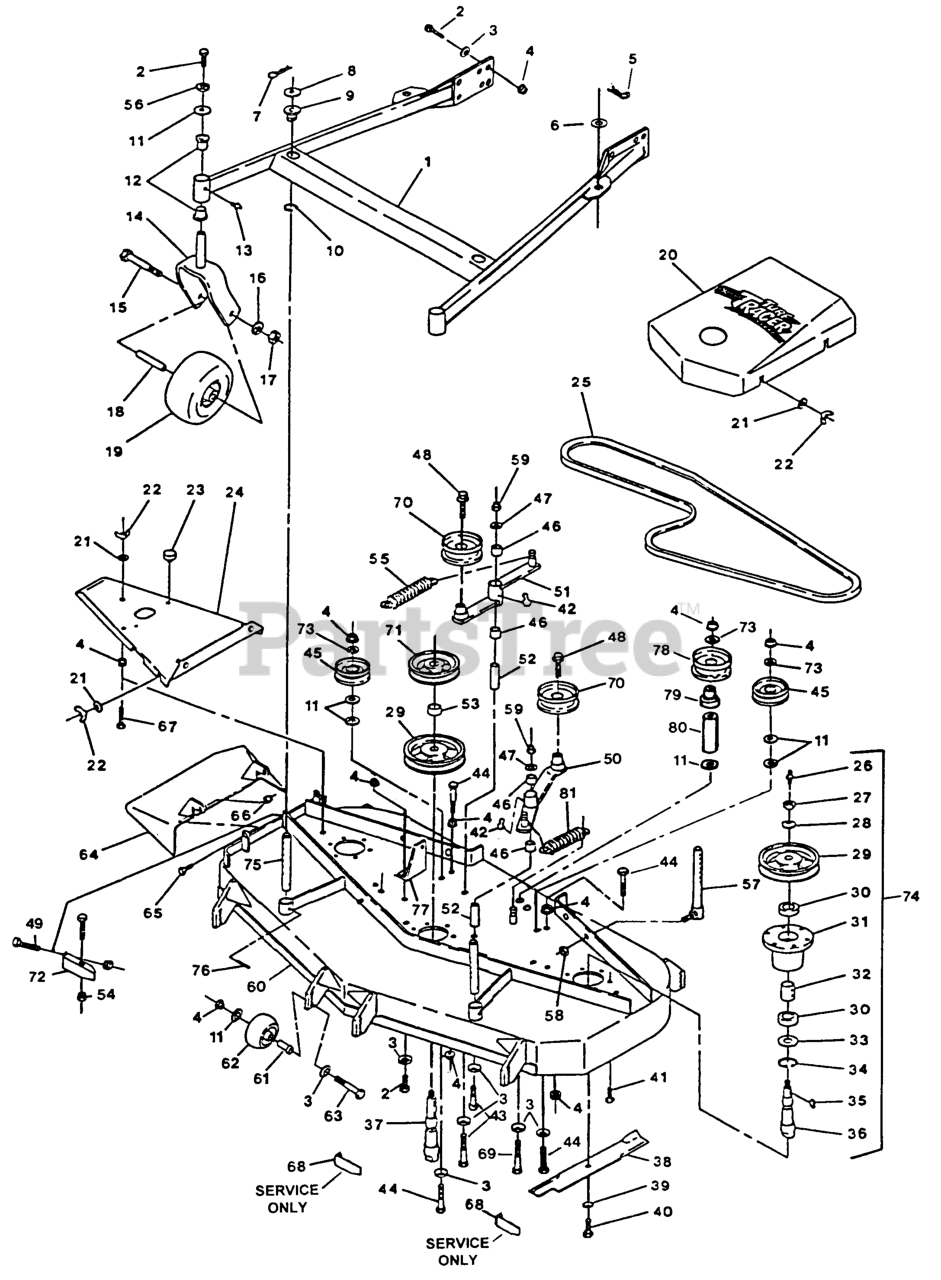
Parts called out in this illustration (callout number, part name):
1	SUPPORT ASSY-FMD60
5	PIN,HAIR COTTER
8	WASHER-FLAT
9	BUSHING-DECK
11	WASHER
12	BEARING-FLANGED
18	SPACER
22	NUT-WING
24	WLD,DECK COVER
25	BELT-DRIVE, BLADE
28	WASHER-SPRING
29	SHEAVE,BLADE DRIVE
32	SPACER,BEARING
33	SEAL,MECHANICAL DUST
34	RING,SNAP WLDS N5000-244
36	SPINDLE-OUTER BLADE
37	SPINDLE-CENTER BLADE
39	WASHER-SPRING
41	SCRW,TPTTE HH
43	SCREW-HH
45	IDLER,PULLEY
46	SLEEVE-BEARING
50	Arm Weldment Deck Drive Idler
51	Arm Weldment - Deck Idler
52	BUSHING-PIVOT, IDLER
53	SPACER-TUBE
55	SPRING-EXTENSION
61	BUSHING-ROLLER
62	ROLLER-SCALP, ANTI
70	IDLER,PULLEY
72	WLD,BAFFLE DISCHARGE
74	CH-52&60 OUTER CUTTR
75	ROD,DECK SUPPORT
77	BRACKET,SPRING ANCHOR
78	PULLEY-IDLER
79	BUSHING,IDLER
80	SPACER-FENDER
81	SPRING-EXTENSION
